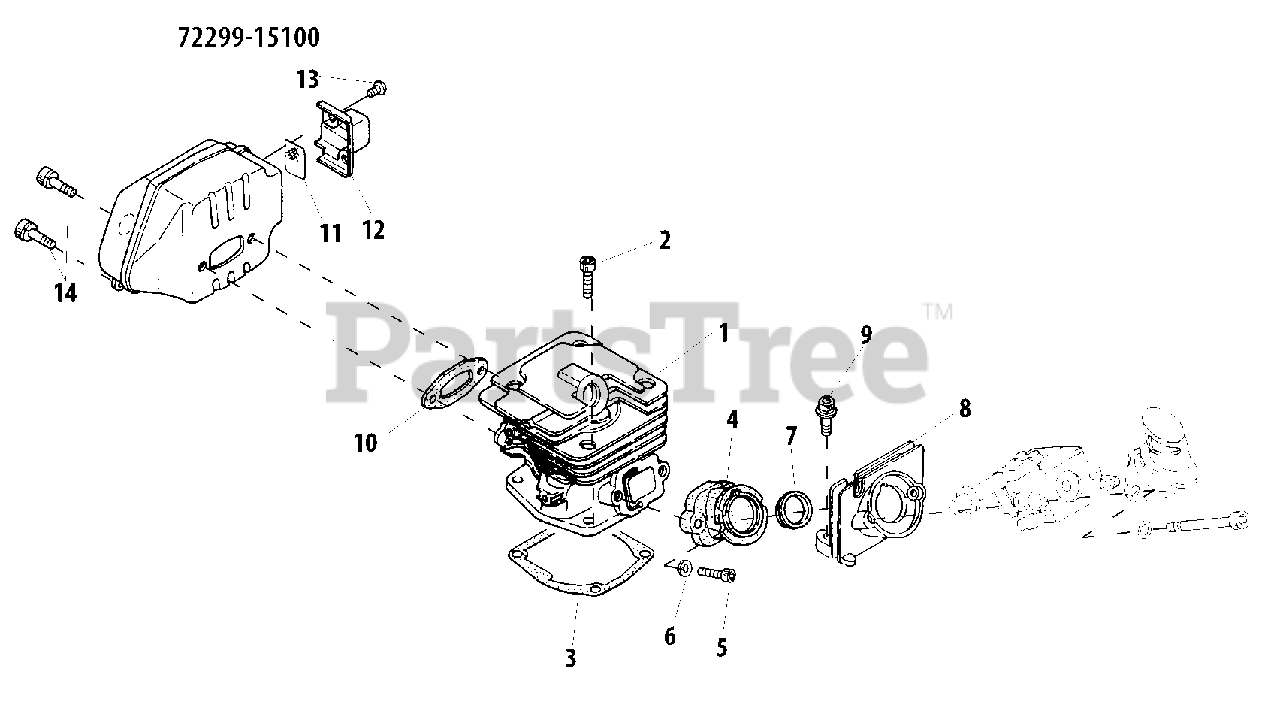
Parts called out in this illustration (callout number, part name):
1	CYLINDER
3	GASKET, CYLINDER
4	BOOT
5	BOLT 4×12
6	WASHER 4 MM
7	COLLAR 16
8	BRACKET
9	BOLT M4×14
10	GASKET, EXHAUST
11	SCREEN, SPARK ARRESTER
12	GUIDE, EXHAUST
13	SCREW M4×6
14	BOLT M5×16
72299-15100	MUFFLER ASSY
